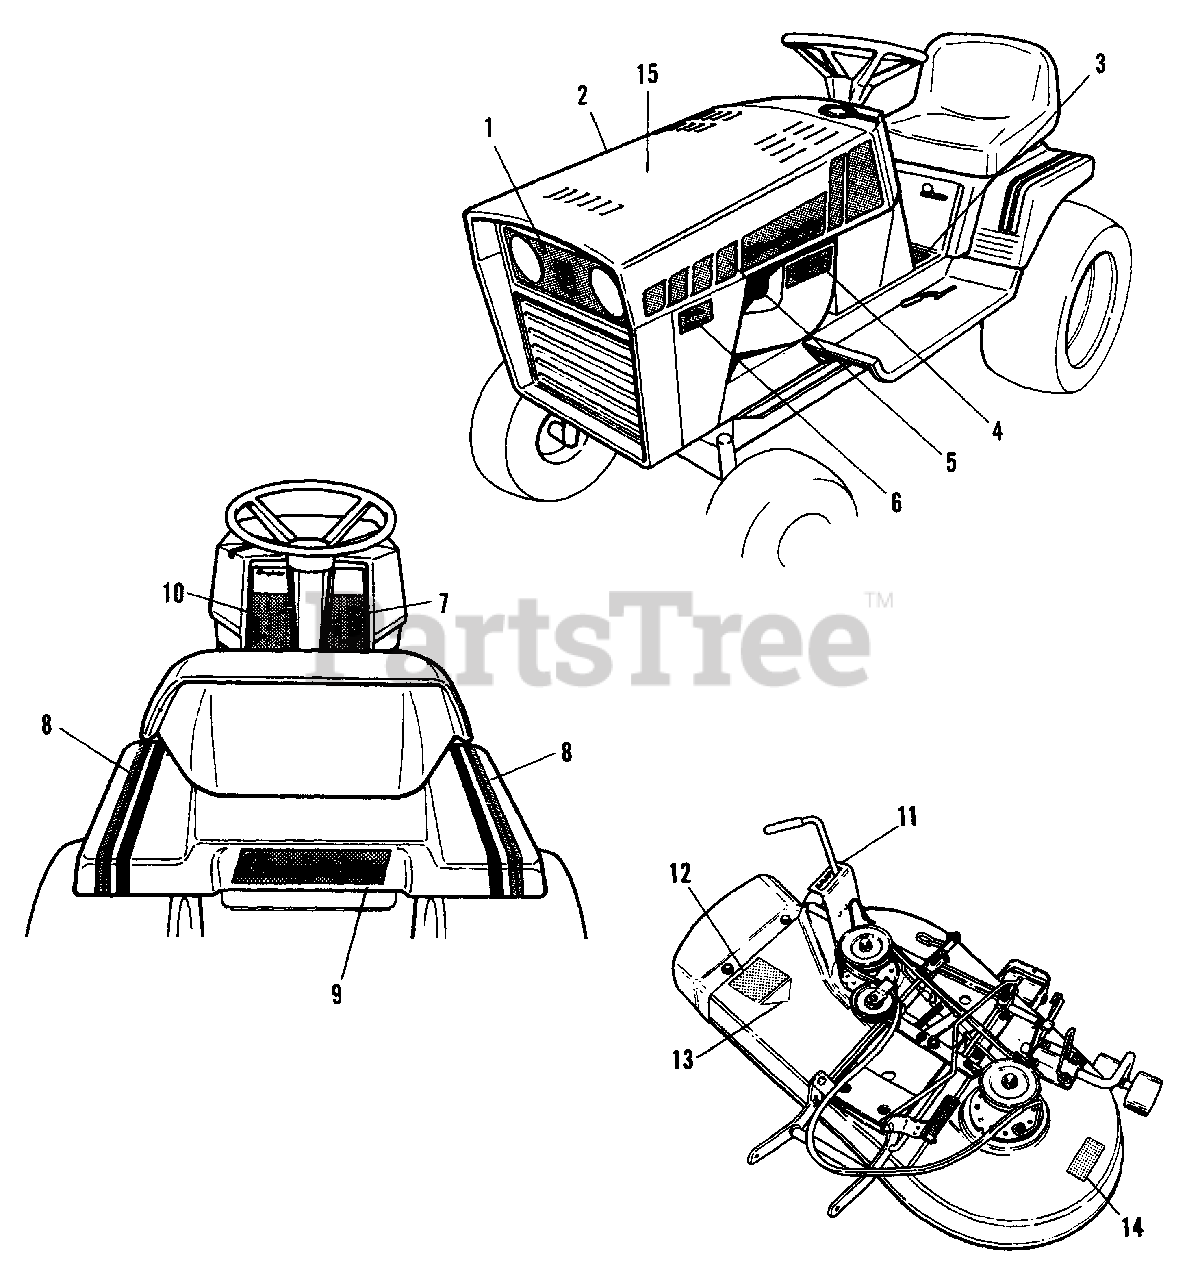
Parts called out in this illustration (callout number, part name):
1	DECAL, Grille
2	DECAL, Hood, R.H.
3	DECAL, Shift
4	DECAL, Engine (1691030, 1691031)
4	DECAL, Engine (1691175, 1691238)
5	DECAL, Hood, L.H.
6	DECAL, 5216 Special (1691030, 1691031)
6	DECAL, 5211 (1691095)
6	DECAL, 5212.5 Special (1691175, 1691238)
6	DECAL, 5212 (1691272)
7	DECAL, Dash, R.H. (1691030, 1691031, 1691175 & 1691238)
7	DECAL, Dash, R.H. (1691095, 1691272)
8	DECAL, Seat Deck
9	DECAL, Simplicity
10	DECAL, Dash, L.H. (1691030, 1691031, 1691175 & 1691238)
10	DECAL, Dash, L.H. (1691095, 1691272)
11	DECAL, Mower Height
12	DECAL, Danger
13	DECAL, OPEI
14	DECAL, Danger
15	DECAL, Drive Belts (Inside Hood)(1691030, 1691031, 1691095, 1691175, 1691238)
15	DECAL, Drive Belts (Inside Hood)(1691272 only)
